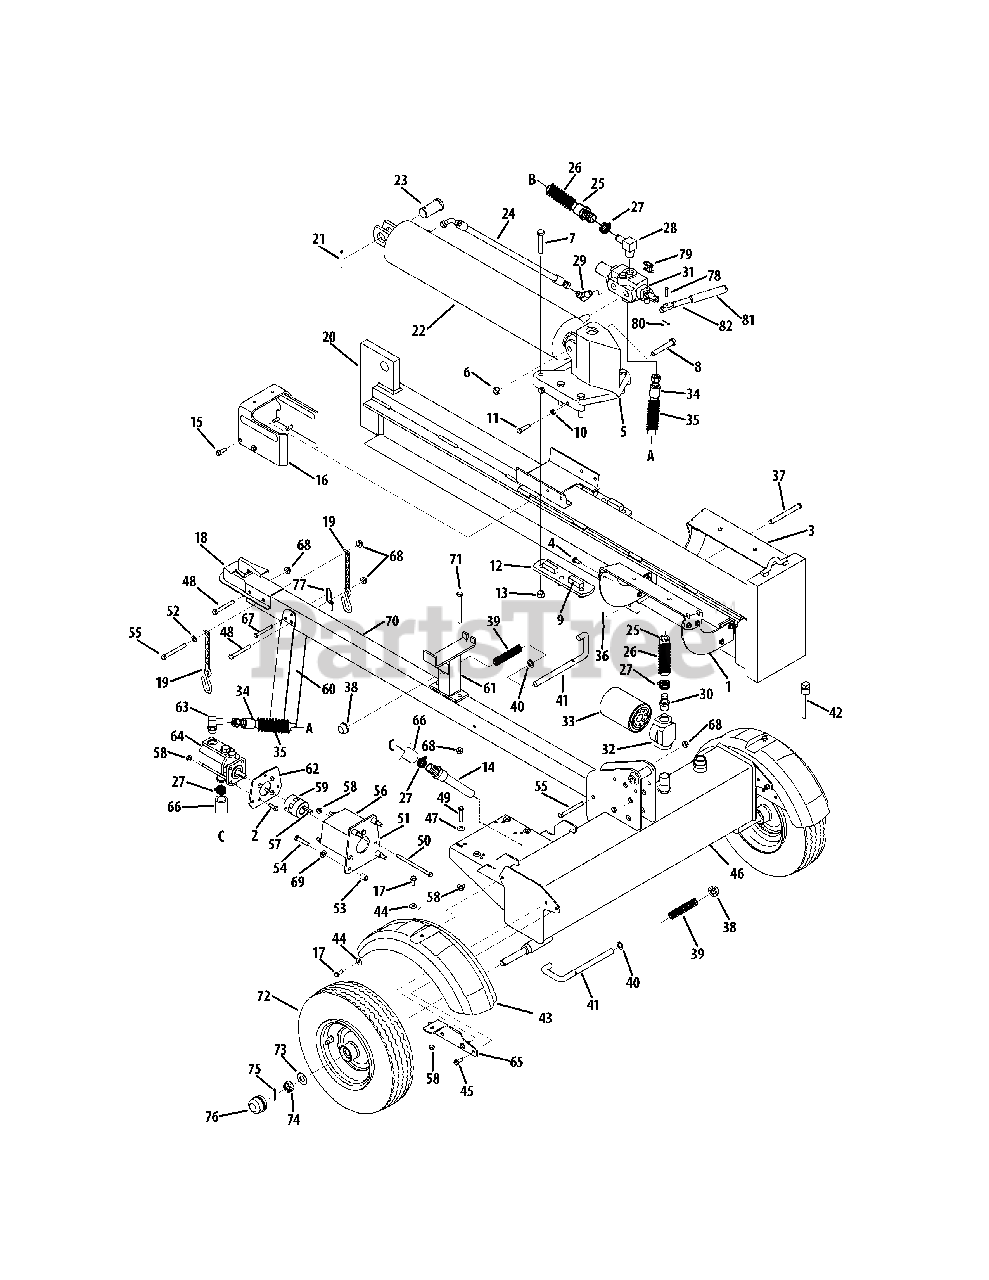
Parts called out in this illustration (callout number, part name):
1	Log Tray Bracket
2	Hex Screw, 5/16-18 x 1.00
3	Log Tray Bracket
4	Self-Tapping Screw, 5/16-18 x .750
5	Wedge Assembly
6	Lock Nut, 1/2-13
7	Hex Cap Screw, 1/2-20 x 2.75
8	Hex Cap Screw, 1/2-13 x 3.25
9	Adjustable Gib
10	Hex Jam Nut, 3/8-24
11	Hex Cap Screw, 3/8-24 x 1.5
12	Back Plate
13	Hex Lock Nut, 1/2-20
14	Inlet Filter
15	Hex Washer Screw, 3/8-16 x 1.000
16	Dislodger
17	Self-Tapping Screw, 5/16-18 x .875
18	Hitch Coupler, 2"
20	Beam Assembly
21	Cotter Pin
22	Hydraulic Cylinder, 31/33 Ton
23	Clevis Pin
24	Hydraulic Hose
25	Return Hose, 3/4" ID x 44"
26	Hose Guard
27	Hose Clamp, 5/8"
28	Return Elbow
29	90 Degree Solid Male Adapter
30	4" Hose Adapter
31	Control Valve
32	Filter Housing
33	Oil Filter
34	High Pressure Hydraulic Hose
35	Hose Guard
36	Cotter Pin, 1/8"
37	Hinge Pin, 1/2 x 4.8" Lg.
39	Compression Spring, 4"
40	Flat Washer, .635 ID x .93 OD
41	Locking Rod
42	Vented Dipstick
44	Flat Washer, .343 x .880 x .062
45	Self-Tapping Screw, 5/16-18 x 1.00
46	Frame Assembly, 7.0 Gal
47	Bell Washer, 340 x .872 x .060
48	Hex Cap Screw, 3/8-16 x 3.00
49	Hex Cap Screw, 5/16-18 x 1.75
50	Hex Cap Screw, 5/16-18 x 5.50
51	Front Support Bracket Coupling
52	Flat Washer, .375 x .738 x .063
53	Spacer, .385 x .623 x .750
54	Hex Cap Screw, 3/8-16 x 1.75
55	Hex Cap Screw, 3/8-16 x 3.50
56	Coupling Shield
58	Hex Flange Lock Nut, 5/16-18
59	Coupling, .500
59	Coupling, 1.00
59	Spider Bushing
59	Set Screw, 1/4-20 x .38
61	Support Beam Assembly
62	Rear Coupling Support Bracket
63	Adapter, 7/8-14
65	Fender Mounting Bracket
66	Suction Hose
67	Clevis Pin, 5/16 x 2.5
68	Flange Lock Nut, 3/8-16
69	Lock Washer, 3/8
70	Tube
71	Hex Cap Screw, 3/8-16 x 4.0
72	Wheel Assembly
72	Wheel/Rim Ass., 16.0 x 4.8 x 8.0
72	Dust Seal
72	Bearing, .75
73	Flat Washer, .76" ID x 1.5" OD
74	Slotted Nut, 3/4-16
75	Cotter Pin, 5/32" x 1-1/4"
77	Spring Pin
78	Clevis Pin
79	Valve Handle Link
80	Cotter Pin
82	Hydraulic Valve Control
